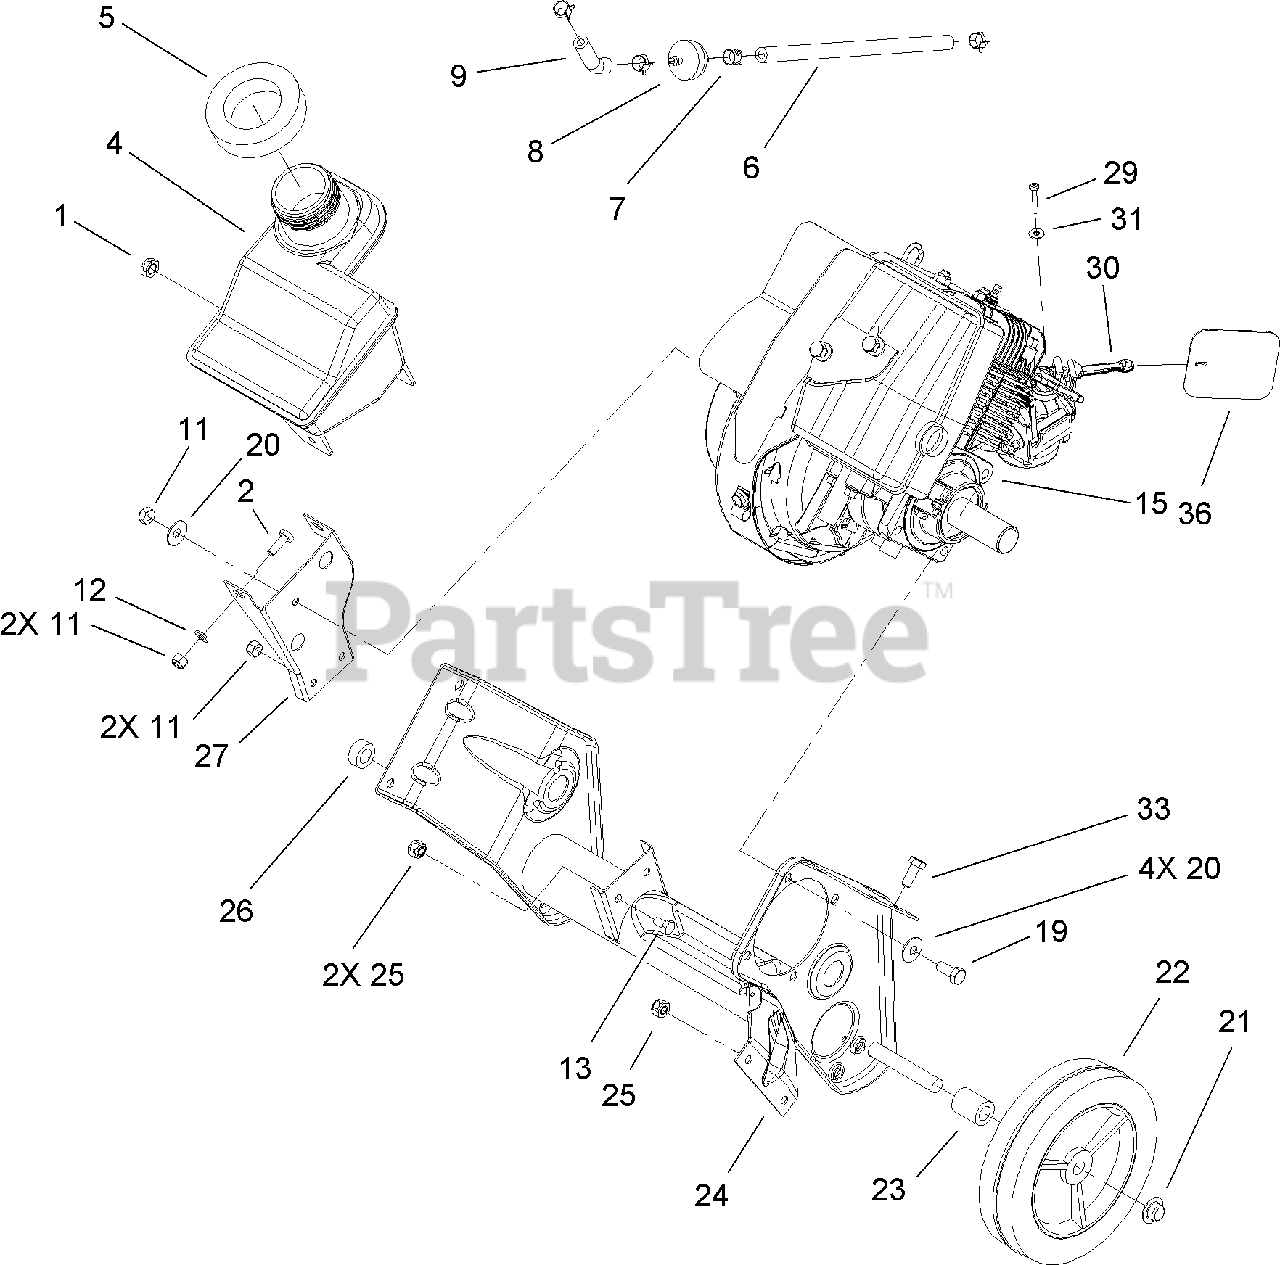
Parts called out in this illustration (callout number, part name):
1	NUT-LOCK, CONE
2	SCREW-HH
5	SEAL-FOAM
6	HOSE-FUEL
8	FILTER-FUEL
9	HOSE-FUEL
11	NUT-LOCK, NI
12	WASHER-FLAT
13	SCREW-HH
19	SCREW-HH
20	WASHER-BELLEVILLE
23	SPACER-WHEEL
25	NUT-LOCK, NI
26	SPACER-WHEEL
27	BRACKET-SUPPORT, RECOIL
29	SCREW-PPH, PLASTITE
30	LEVER-CHOKE
31	WASHER-FLAT
33	SCREW-HH
36	SHIELD-CHOKE HOLE
